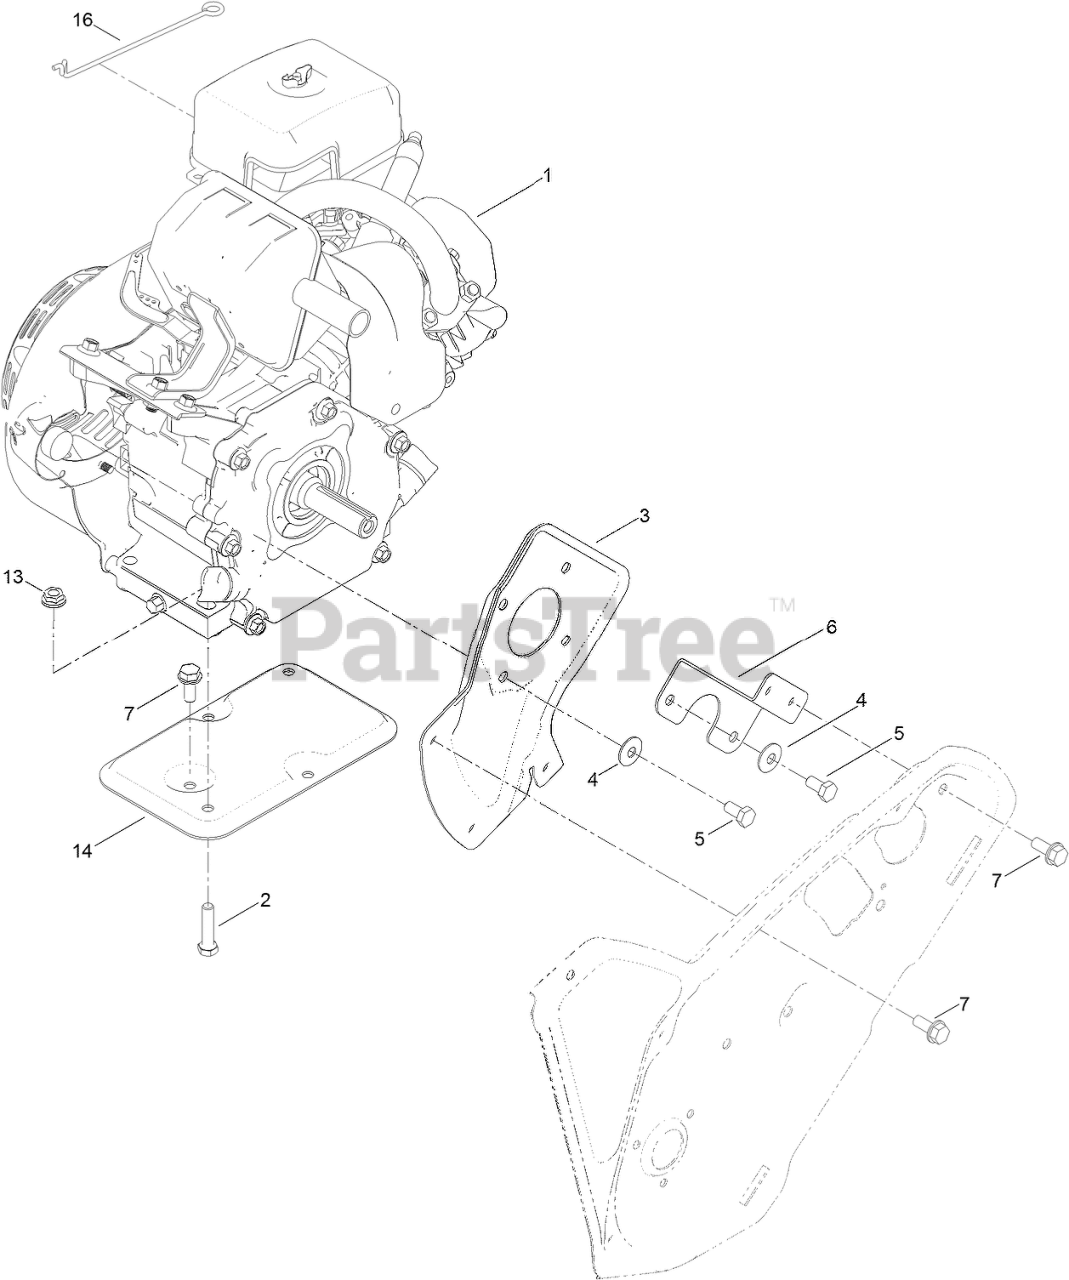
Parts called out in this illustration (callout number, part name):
1	ENGINE-170FS-2
2	SCREW-HH
3	PLATE-ENGINE, PTO
4	WASHER-BELLEVILLE
5	SCREW-HH
6	SUPPORT-ENGINE, SIDE
7	SCREW-HWHTF
13	NUT-HF
14	SUPPORT-ENGINE
16	LINK-KNOB, CHOKE
